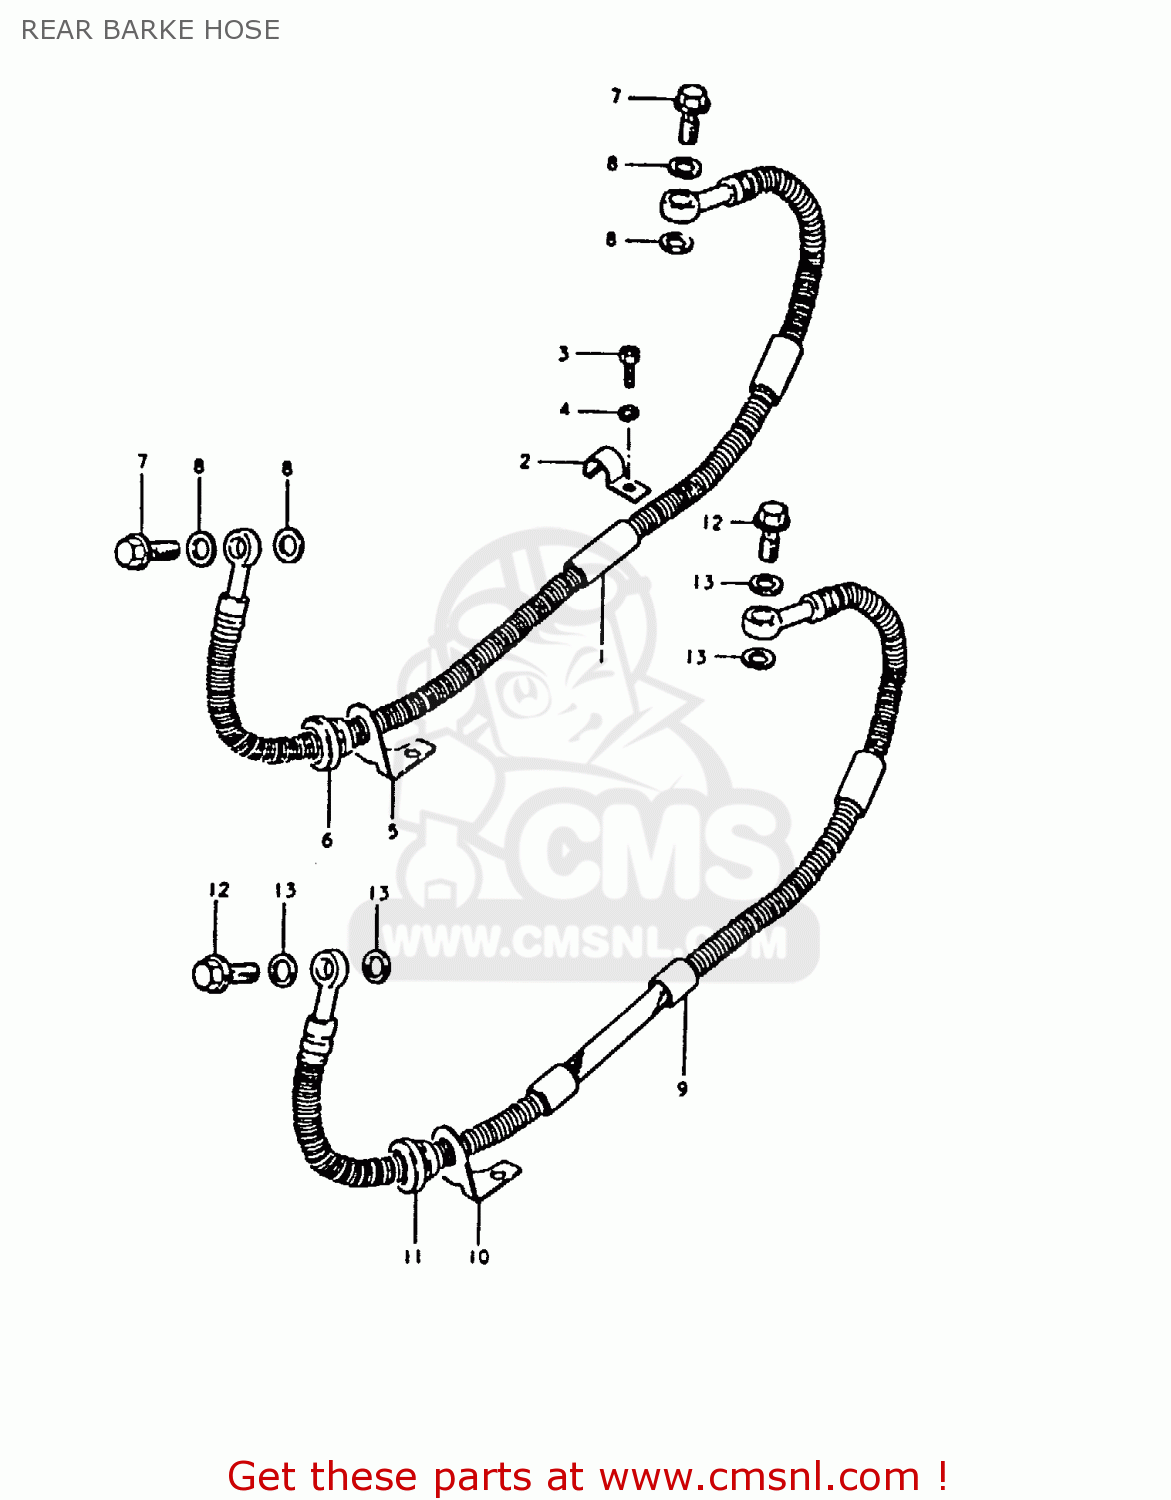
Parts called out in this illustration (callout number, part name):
1	HOSE,REAR BRAKE
2	CLAMP,REAR BRAKE HOSE
3	SCREW(6X8)
4	LOCK WASHER
5	GUIDE,BRAKE HOSE
6	GROMMET,BRAKE HOSE GUIDE
7	BOLT,UNION
8	WASHER
9	HOSE,REAR BRAKE
10	GUIDE,BRAKE HOSE
11	GROMMET,BRAKE HOSE GUIDE
12	BOLT,UNION
13	WASHER
